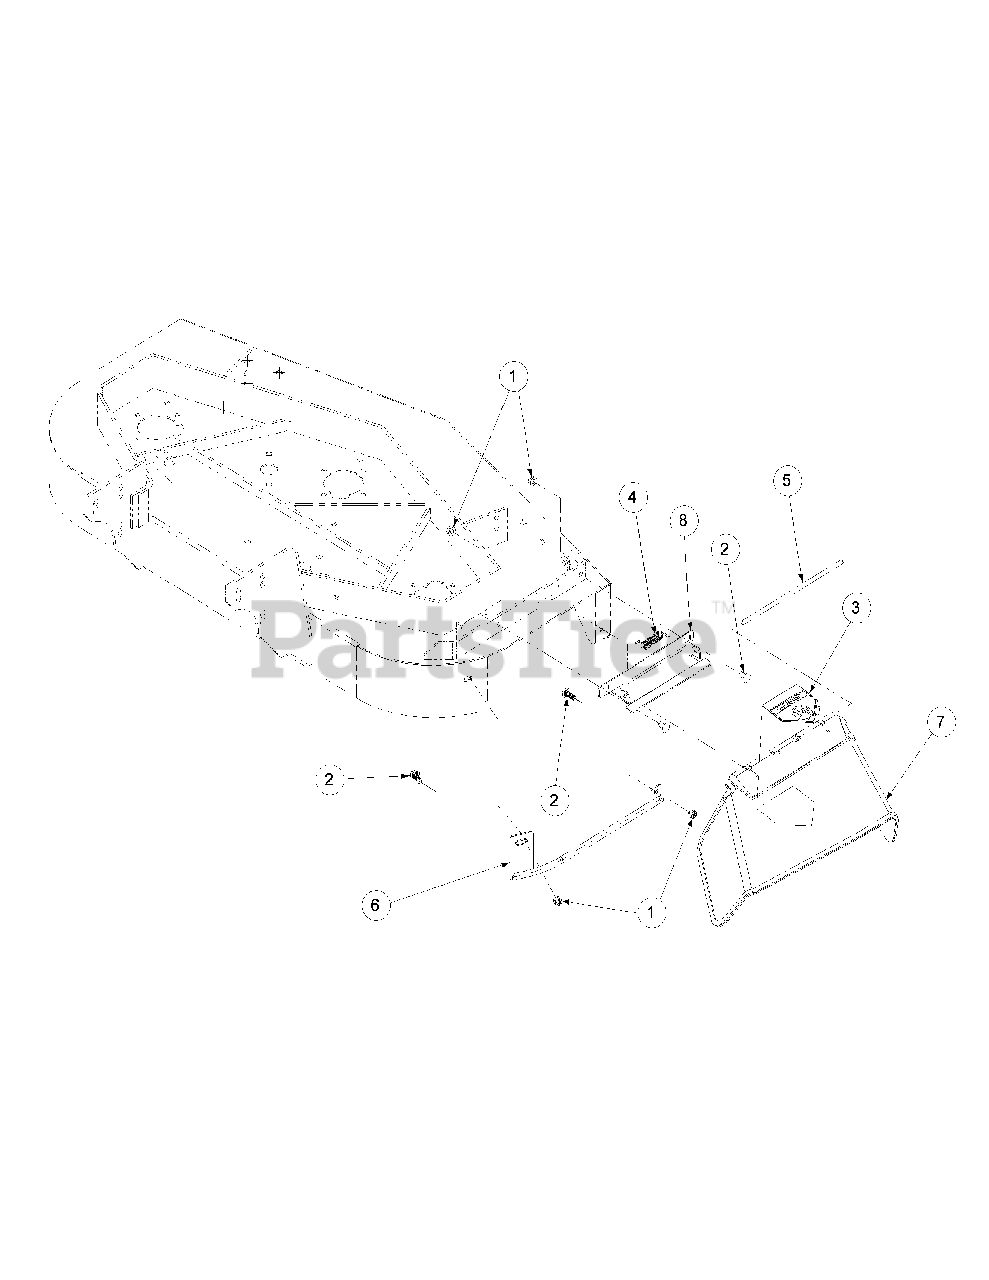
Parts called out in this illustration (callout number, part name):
1	Hex Nut Flange Lock, 3/8-16
2	Carriage Bolt, 3/8-16 x1.00 LG.
3	Decal, Danger Hands & Feet
4	Torsion Spring, 0.4 ID x 2.16 LG
5	Chute Deflector Rod
6	Stiffner Assembly, 48
7	Deflector Chute
8	Deflector Chute Bracket
